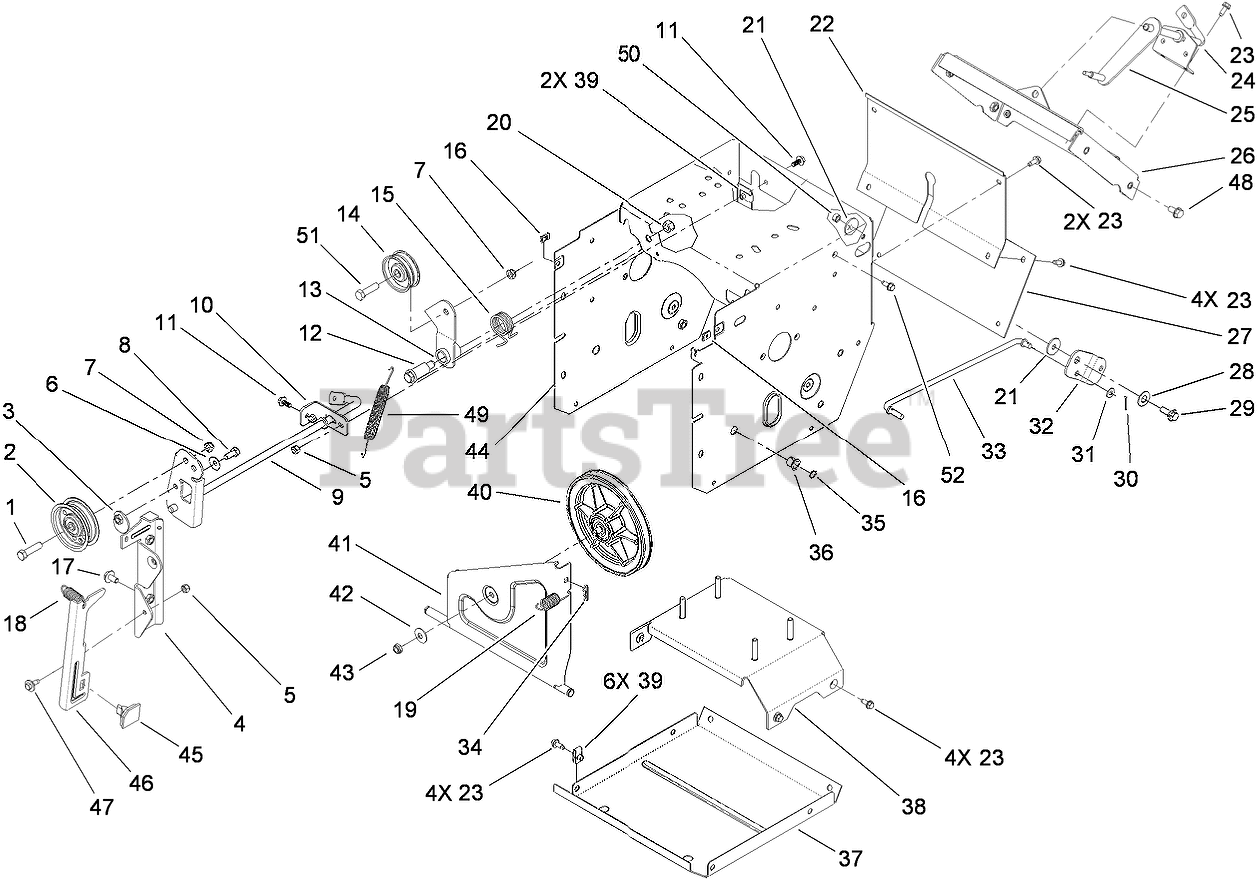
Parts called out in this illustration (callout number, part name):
1	SCREW-HH
2	PULLEY-IDLER
4	BRACKET-IDLER, IMPELLER
5	NUT-LOCK, NI
6	WASHER-BELLEVILLE
7	NUT-LOCK, NI
8	SCREW-HH
9	IMPELLER CLUTCH ASM
10	BRACKET-REAR, CLUTCH
11	SCREW-HHF
12	BOLT-SHOULDER
13	ARM-IDLER, TRACTION
14	PULLEY-IDLER
15	SPRING-TORSION
16	NUT-SPEED, U-TYPE
17	SCREW-HHF
18	SPRING-EXTENSION
19	SPRING-EXTENSION
20	NUT-LOCK, NI
21	WASHER-PIVOT
22	COVER-UPPER
23	SCREW-HWH
24	BRACKET-ROD, SHIFT
25	LEVER-CONTROL, TRACTION
26	SHIFT PLATE ASM
27	COVER-LOWER
28	WASHER
29	SCREW-SHOULDER
30	PIN-COTTER
31	WASHER-PLAIN
32	BELLCRANK-DRIVE
33	LINK-CONTROL, SPEED
34	PIN-COTTER
35	RING-RETAINING
36	BUSHING-NYLINER
37	PAN-BOTTOM
38	FRAME BRACE ASM
40	PULLEY-TRACTION
41	BRACKET-WHEEL, FRICTION
42	WASHER-BELLEVILLE
43	NUT-HEX
44	TRACTION FRAME ASM
45	PAD-BRAKE
46	ARM-BRAKE
47	SCREW-SHOULDER
48	SCREW-HWHTF
49	SPRING-EXTENSION
50	NUT-LOCK, NI
51	SCREW-HH
52	SCREW-HWH
